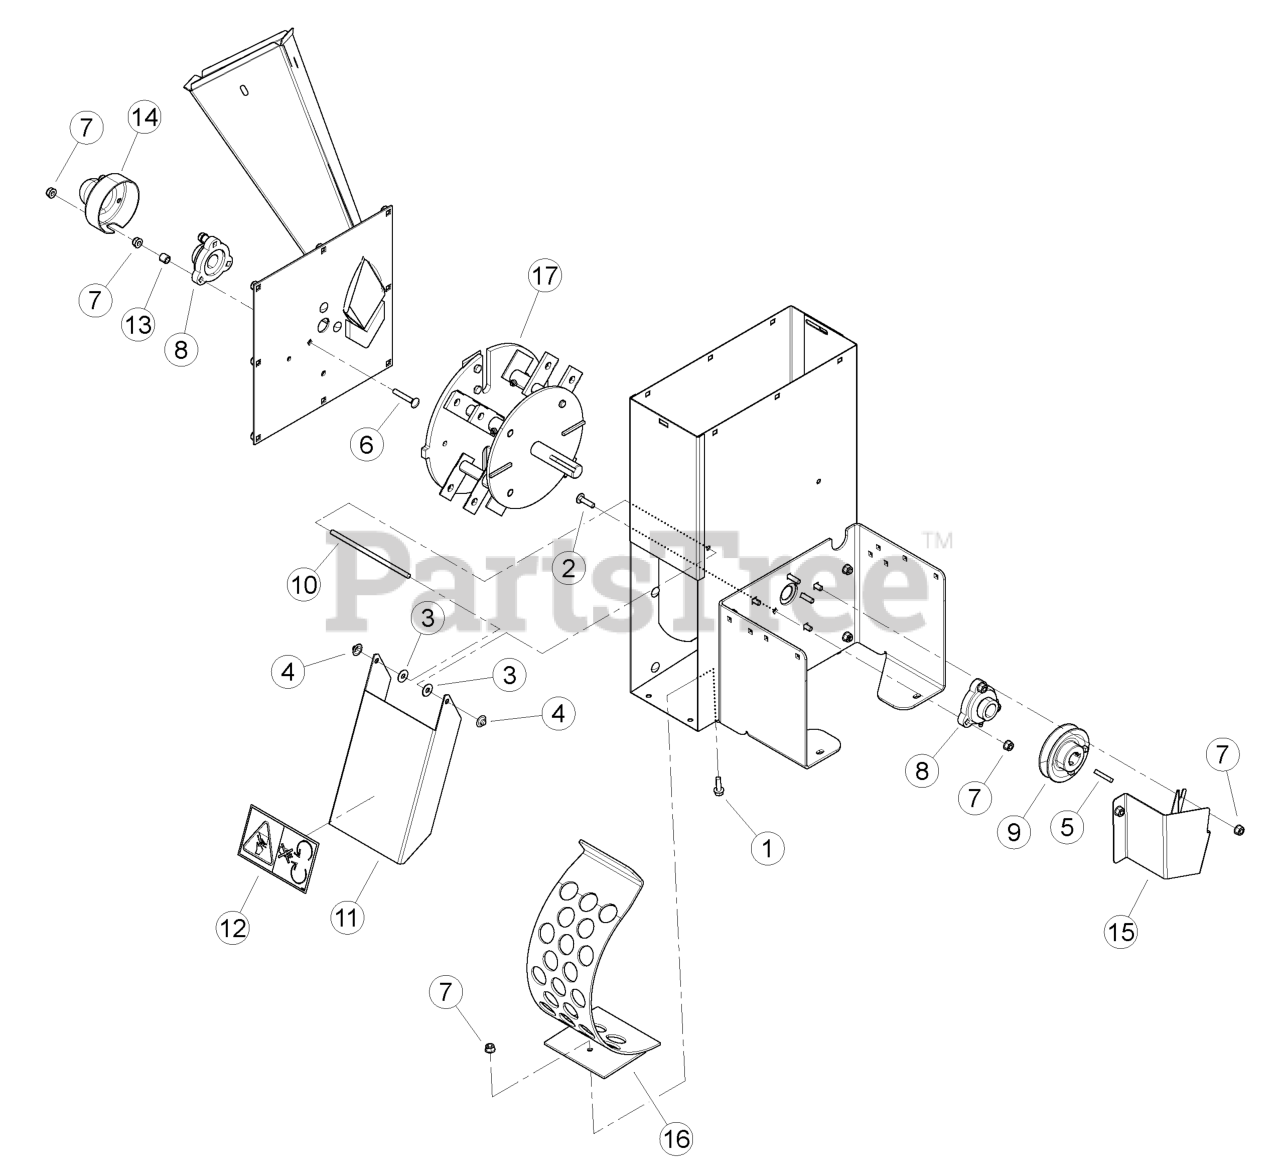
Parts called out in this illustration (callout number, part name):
1	BOLT, 5/16 × 1 FLANGE NC
2	BOLT, 5/16 × 1-1/4 GR5 CRG
3	WASHER, 5/16" ID 7/8" OD NYLON FLAT
4	PUSHNUT, 5/16" ZP
5	KEY, 1/4 SQ × 1-1/2 LG PLAIN
6	BOLT, 5/16 × 2" GR5 CRG NC ZP
7	NUT, 5/16-18 NYLOCK FLANGE
8	BEARING, 1" FLUSH MOUNT CAST W/ COLLAR
9	PULLEY, CAST 4" OD 1" BORE B GRV
10	SHAFT, DOOR PIVOT
11	DOOR, 3 5 HP DISCHARGE W/ DECAL
12	DECAL, BLADE DANGER ISO
13	SPACER, .54 OD × .50" LG
14	CAP, ROTOR SHAFT END CAP RENTAL
15	SHIELD, LOWER
16	WELDMENT, NARROW COARSE TAPERED
17	ASSEMBLY, 3" NARROW ROTOR KNIVES
